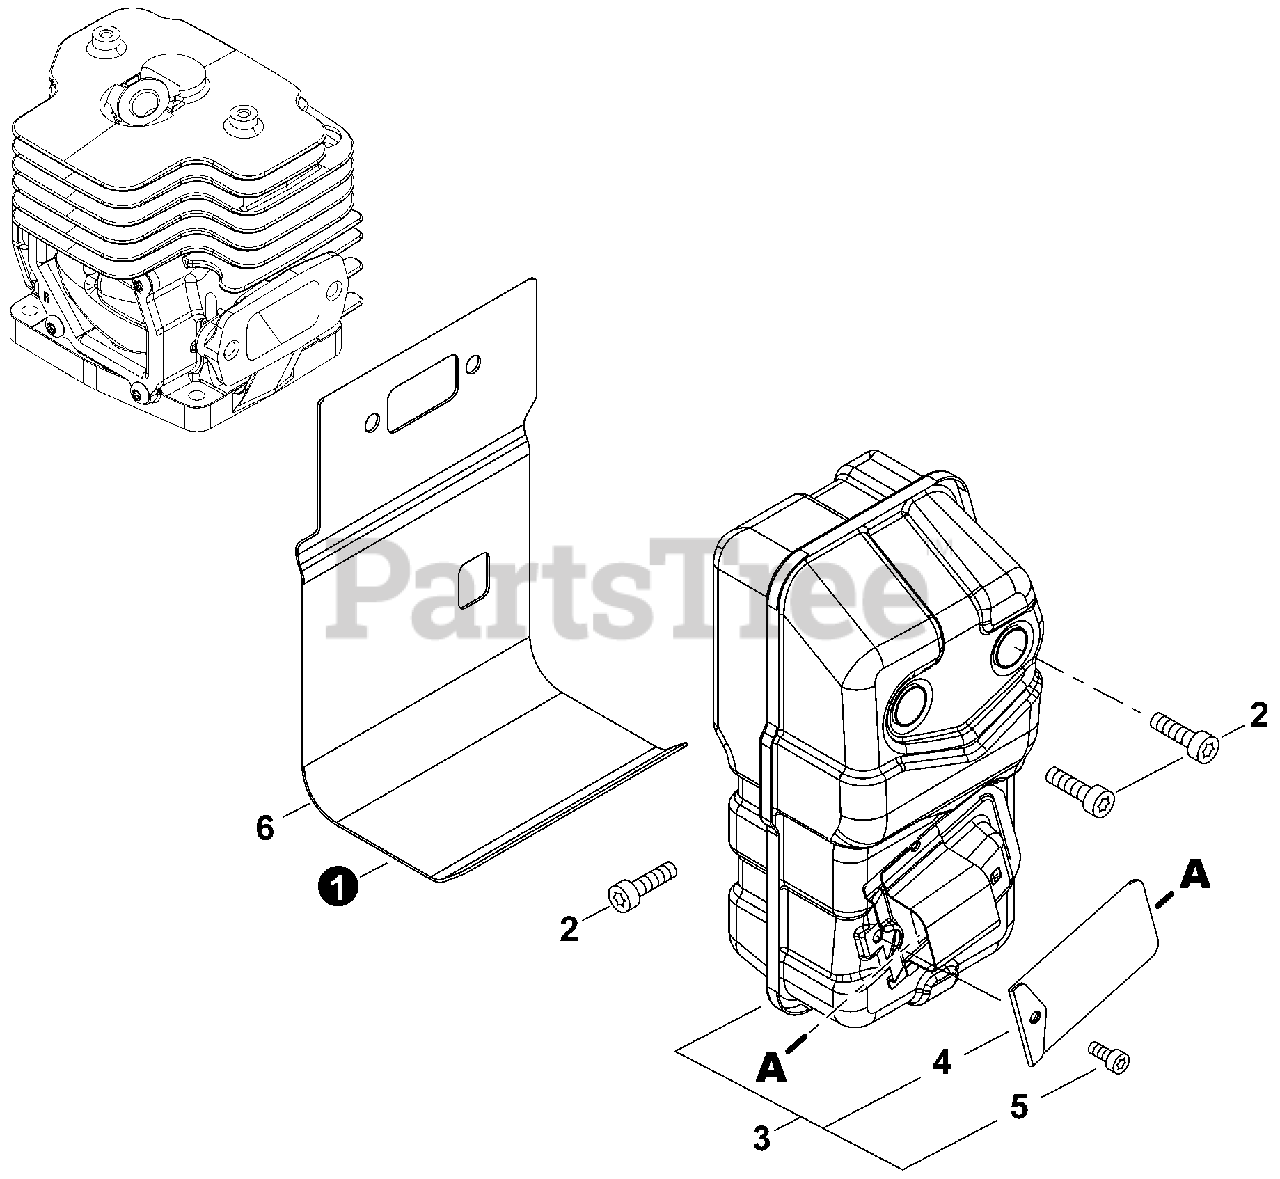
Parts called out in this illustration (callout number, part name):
1	HEAT SHIELD, EXHAUST
2	BOLT, TORX 6x20
3	MUFFLER ASSY
4	SCREEN, SPARK ARRESTER
5	BOLT, TORX 4x8
6	GASKET KIT: ENGINE, INTAKE, EXHAUST
